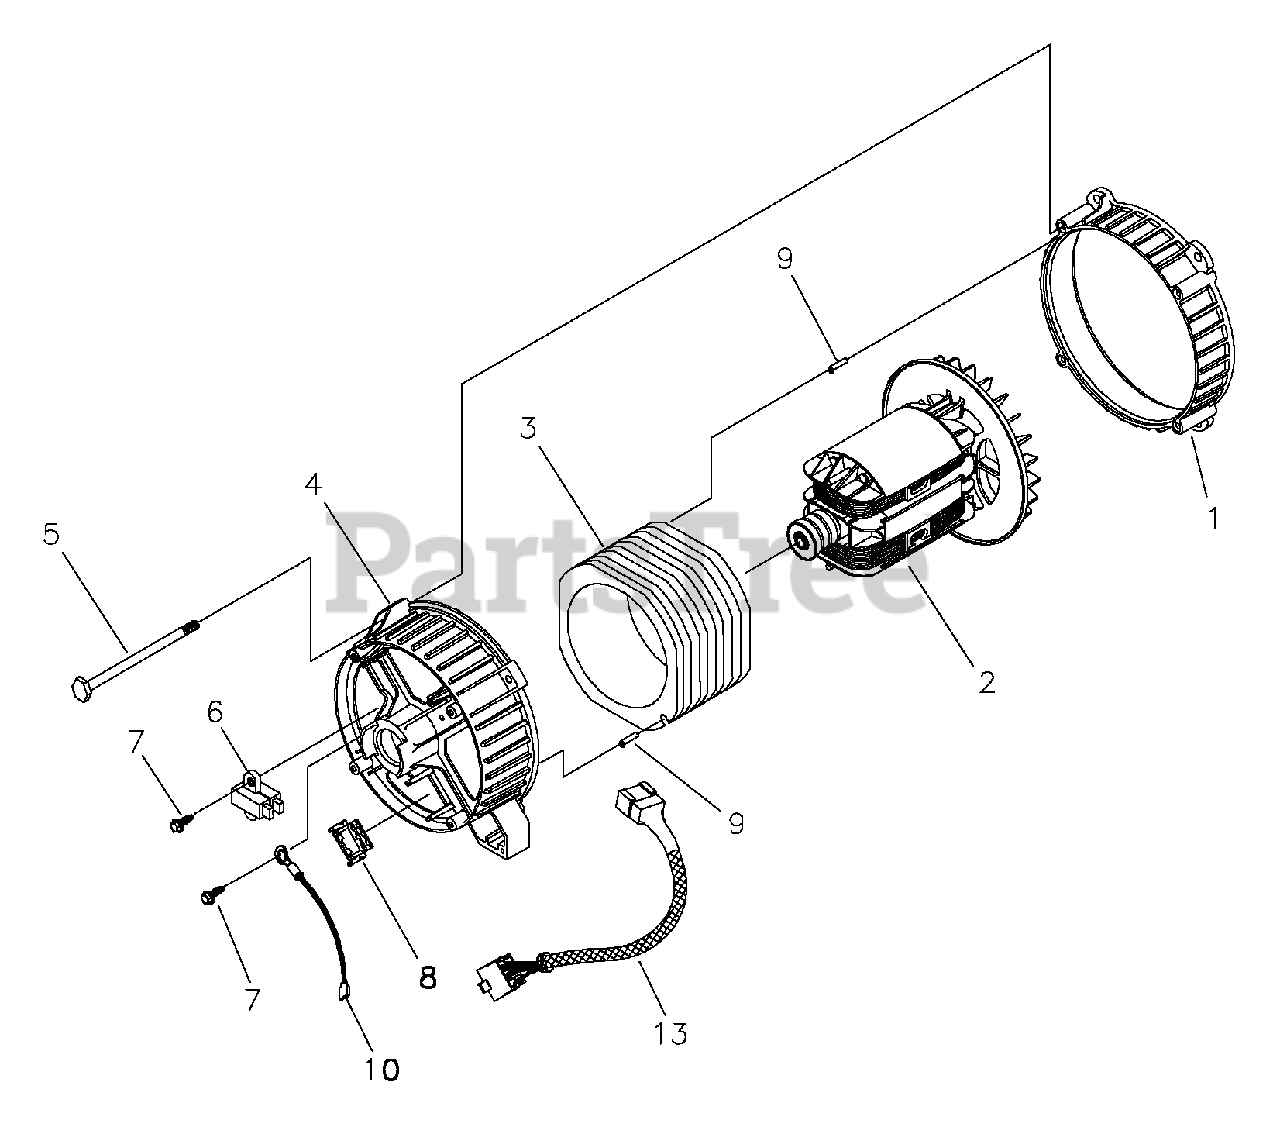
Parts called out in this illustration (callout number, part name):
1	ADAPTER, Mounting,Alternator
4	RBC, with O-Ring (p/n 189197GS)
5	HHCS, M6 - 1.0 x 140 SEMS
6	ASSY, Holder, Rectifier/Brush
7	TAPTITE, M5 - 0.8 x 16
8	RECEPTACLE, 6 pin
9	PIN, Roll, 4mm x 10
10	ASSY,Wire, Ground
13	HARNESS,Wire, Power
